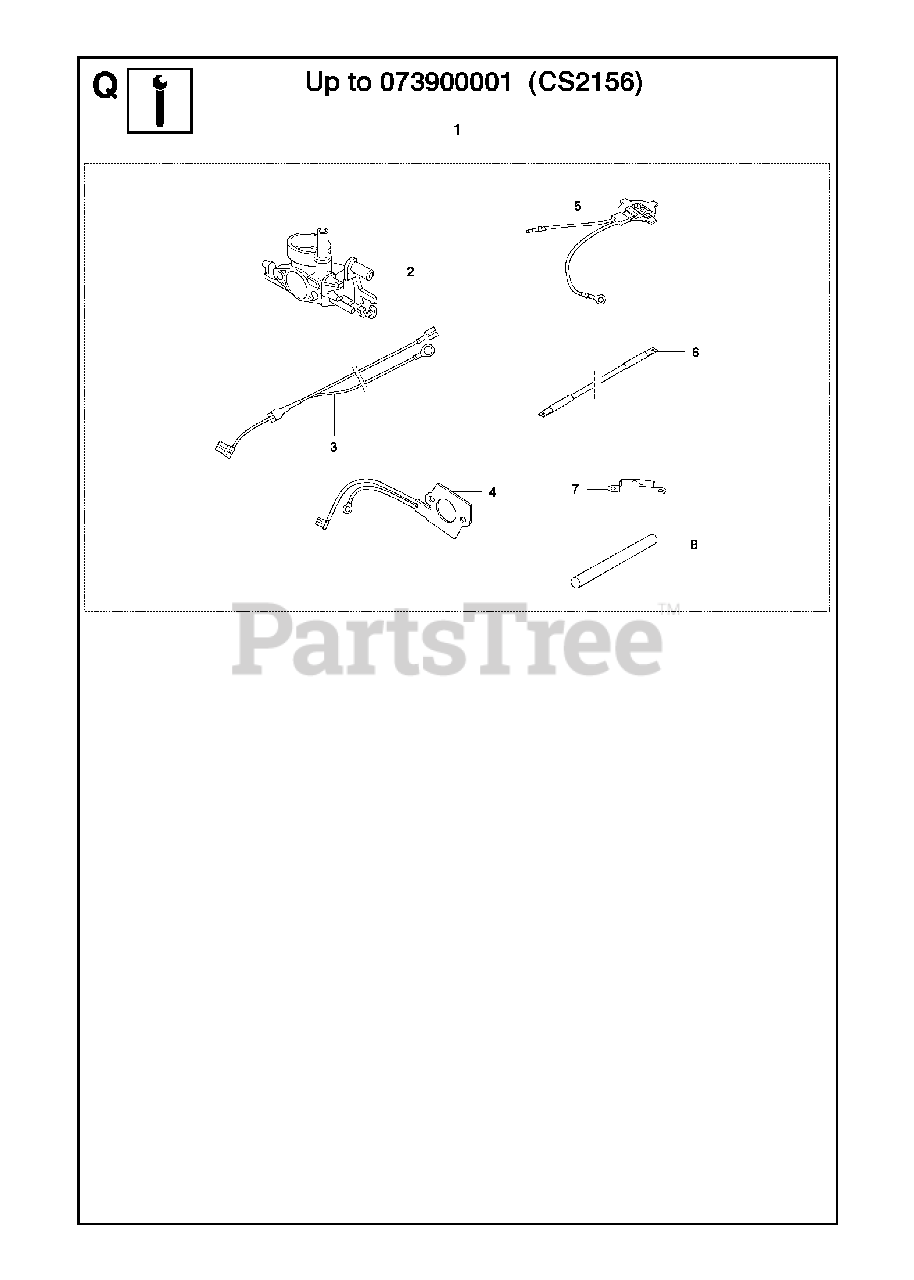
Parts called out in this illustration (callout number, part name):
2	FILTER HOLDER
3	WIRING ASSY
4	HEATING PLATE
5	THERMOSTAT ASSY
6	WIRING ASSY
7	RETAINER
8	CABLE COVER
